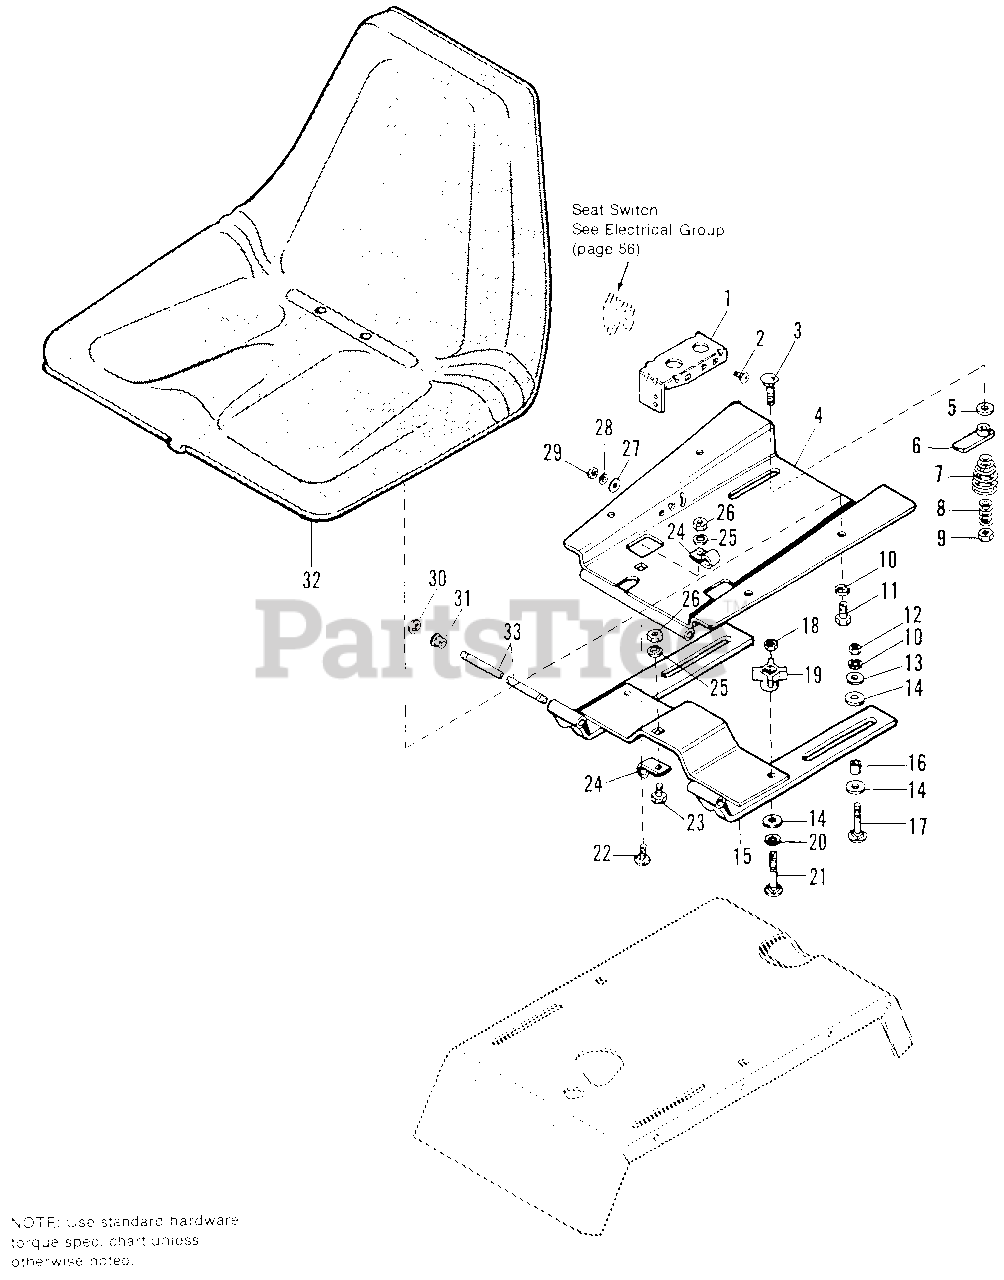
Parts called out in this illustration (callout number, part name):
1	BRACKET, Seat Switch
2	BOLT, Carriage, #10-24 x 1/2, Gr. 5
3	BOLT, Carriage, 5/16-18 x 1-1/4, Gr. 5
4	HINGE & PIVOT ASSY., Upper Seat
5	WASHER, Plain, 21/64 ID x 1-1/4 OD x 14 Ga
6	LEVER ASSY., Seat Spring
7	SPRING, Seat
8	SPRING, Seat Switch
9	NUT, Centerlock, Flange, 5/16-18
10	LOCKWASHER, 5/16
11	CAPSCREW, Hex Hd., 5/16-18 x 5/8, Gr. 5
12	NUT, Hex, 5/16-18
13	WASHER, Flat, 11/32 x 1 x 1/8
15	HINGE ASSY., Lower Seat
16	SPACER, Seat Hinge
17	BOLT, Carriage, 5/16-18 x 1, Gr. 5
18	NUT, Centerlock, 5/16-18
20	NUT, Push On
21	BOLT, Carriage, 5/16-18 x 2-1/4
22	BOLT, Carriage, 1/4-20 x 3/4, Gr. 5
23	CAPSCREW, 1/4-20 x 5/8, Gr. 5
24	CLAMP, Closed
25	LOCKWASHER, 1/4
26	NUT, Hex, 1/4-20
27	WASHER, Flat, #10
28	LOCKWASHER, #10
29	NUT, Hex, #10-24
30	RING, Retaining
31	BEARING, Nylon
33	ROD, Seat Hinge
